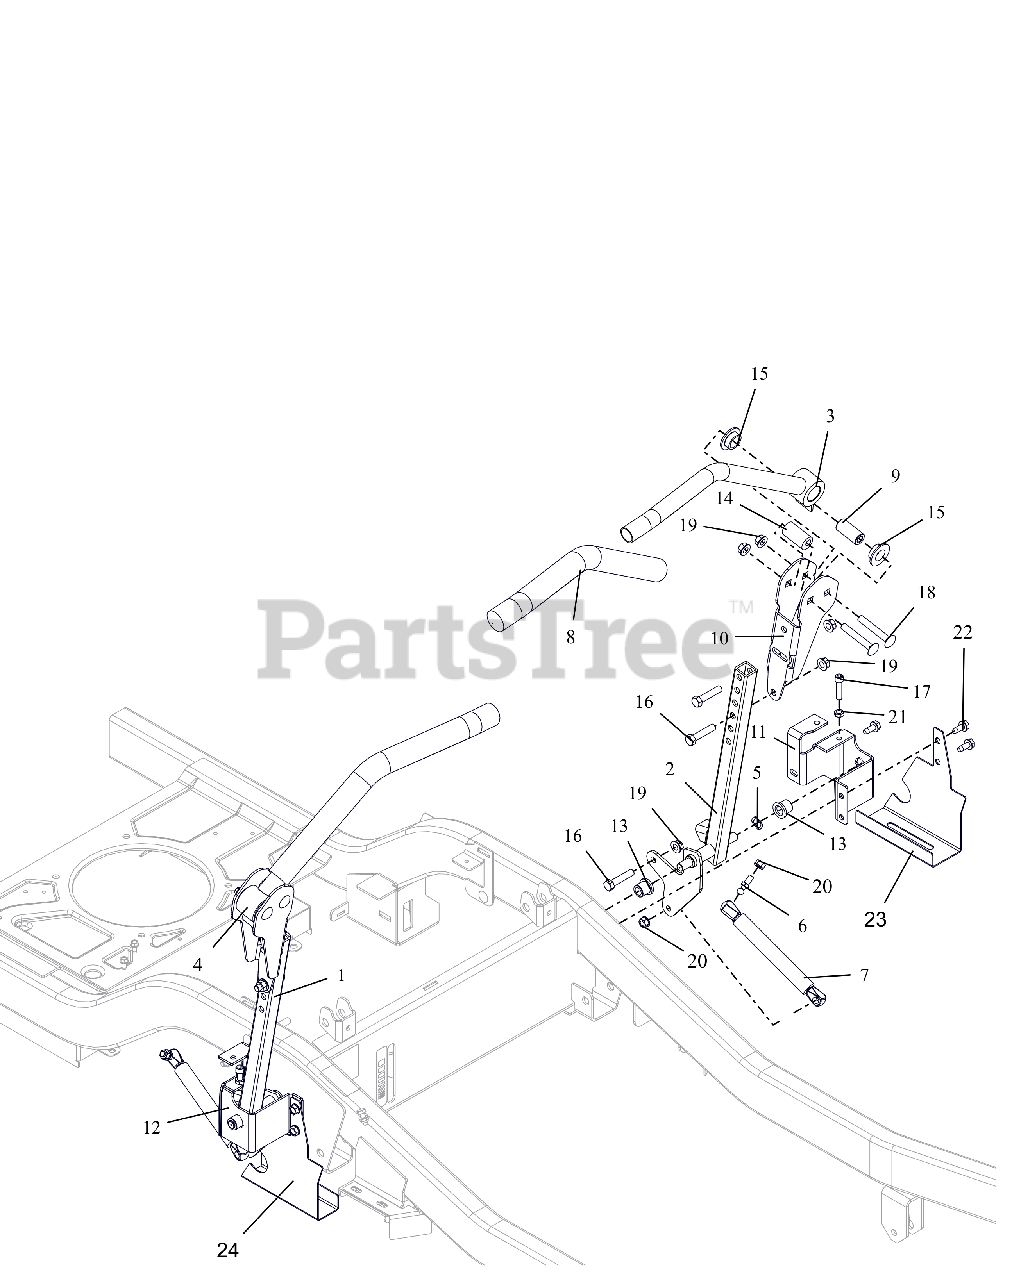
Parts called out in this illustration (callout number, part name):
1	WLDMT, STEERING RH
2	WLDMT, STEERING LH
3	WLDMT, CONTROL HANDLE- BLK
4	WLDMT, CONTROL HANDLE- BLK
5	WAVE WASHER .531X.781X.125FH
6	STUD- BALL
7	DAMPER
8	GRIP, HANDLEBAR
9	SPACER, STEERING ARM
10	ADJ UPPER CONTROL ARM BRKT-BLK
11	BRKT, STEERING ARM MOUNT -LH
12	BRKT, STEERING ARM MOUNT -RH
13	BHSG-FLG .500X.750X.750X.125
14	BSHG, ECCENTRIC.406X.875X1.625
15	BSHG-FLG .762X1.48X.44 NYL
16	BLT, HEX .38-16X1.75 G5 ZCC
17	BLT, SHCS .312-18X1.25 G8 SS
18	BLT, RHSSN.38-16X2.50 G5 ZCC
19	NUT-LK-TOP-FLG .38-16 ZC120
20	NUT,LK-CTR-FLG .31-18 GF ZCC
21	NUT-JAM .312-18 G2 ZCC
22	SCR,TAP .312-18X.75 HWH TR ZCC
23	GUARD, FRAME RAIL BELT LH (BLACK)
24	GUARD, FRAME RAIL BELT-RH (BLACK)
